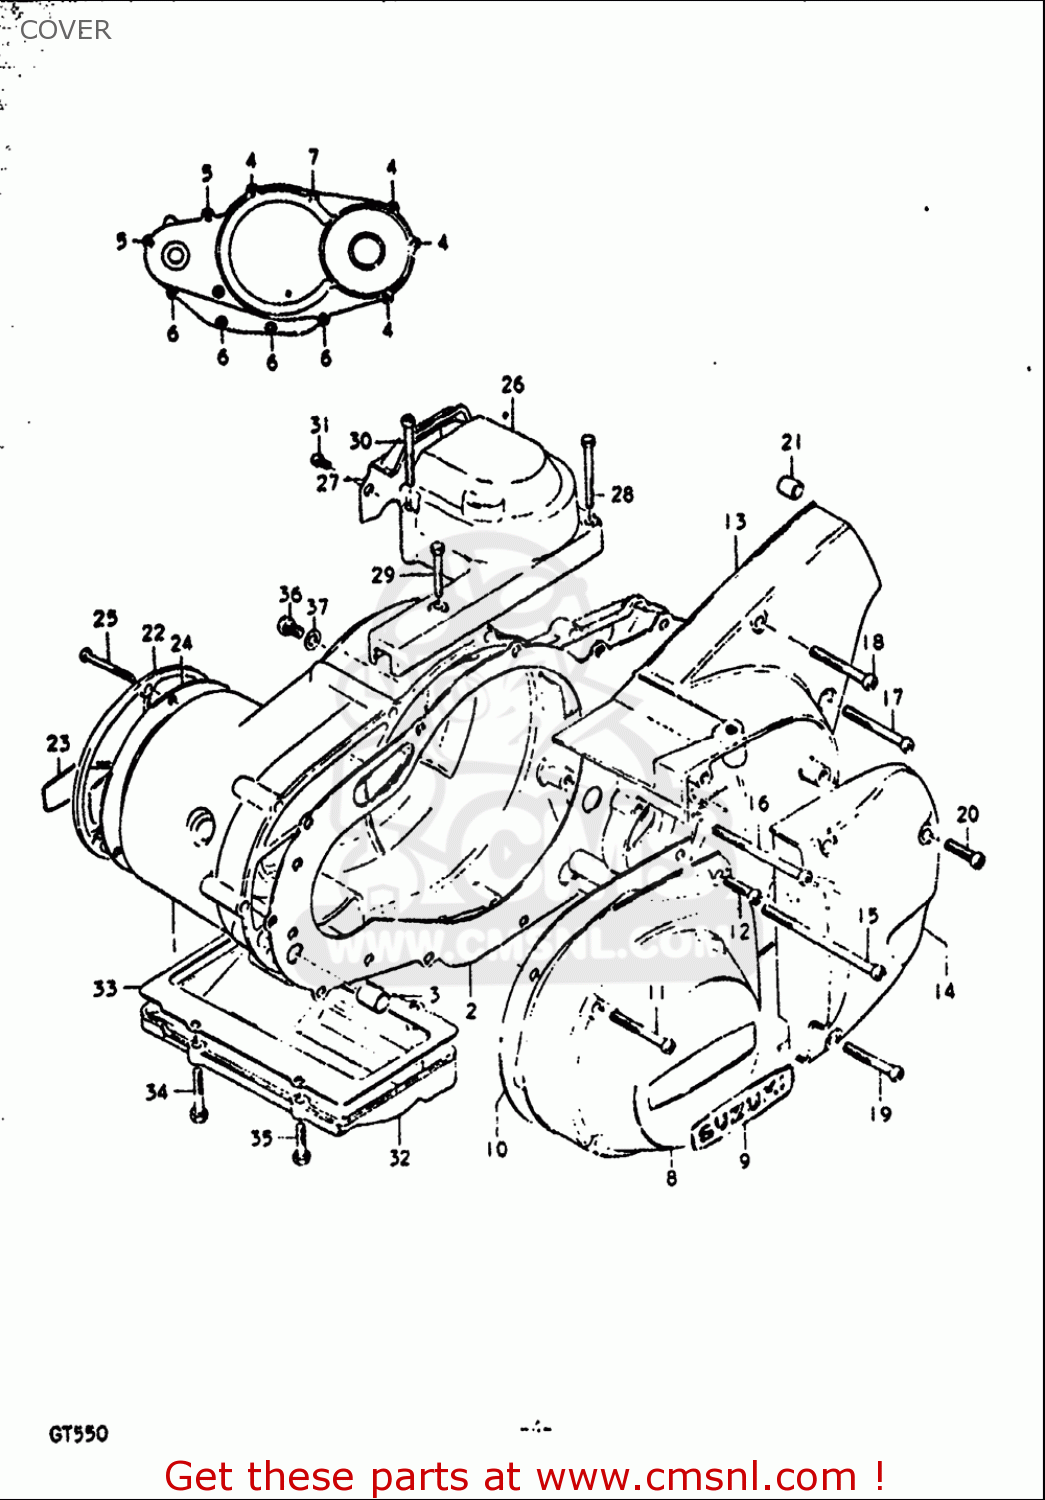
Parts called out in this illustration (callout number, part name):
2	GASKET,CLUTCH COVER
3	PIN
4	SCREW
5	SCREW
6	SCREW
7	SCREW
9	EMBLEM,CONTACT BREAKER CAP
10	GASKET,MAGNETO COVER (MCA)
11	SCREW
12	SCREW
15	SCREW
16	SCREW
17	SCREW
18	SCREW
19	SCREW
20	SCREW
21	PIN
23	EMBLEM,CONTACT BREAKER CAP
24	GASKET,CONTACT BREAKER CAP (NAS)
25	SCREW
28	BOLT 5X45
29	BOLT
30	SCREW
31	SCREW
34	BOLT
35	BOLT 5X20
36	SCREW(6X10)
37	GASKET(6.2X11X1) (NAS)
